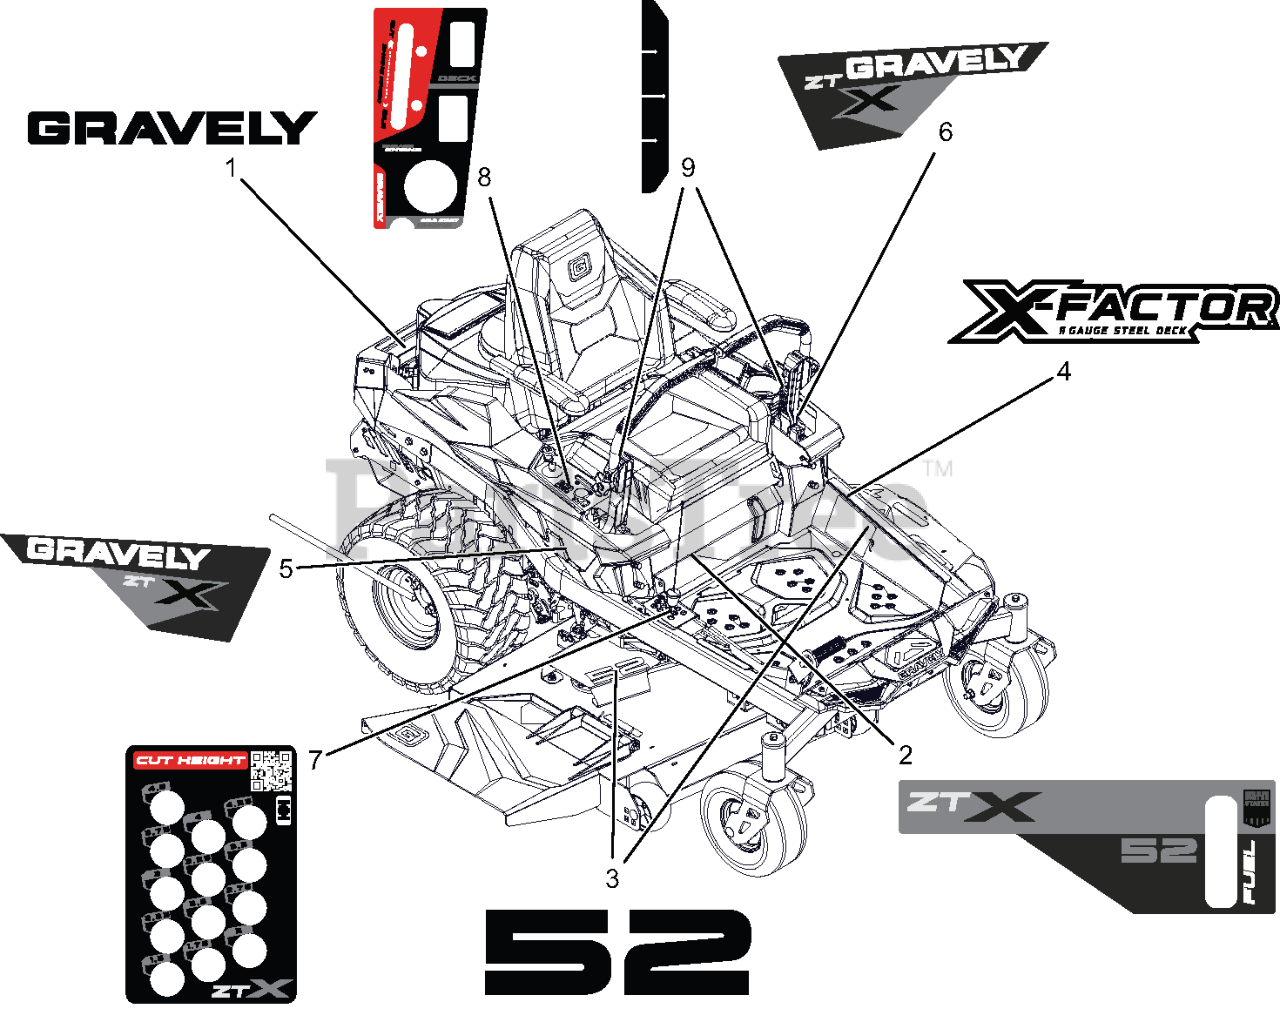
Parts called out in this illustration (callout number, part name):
1	DECAL- GRAVELY
2	DECAL- ZTX 52-KICK PLATE
3	DECAL- DECK 52"
4	DECAL- DECK X-FACTOR
5	DECAL- ZT X FENDER RH
6	DECAL- ZT X FENDER LH
7	DECAL- HEIGHT OF CUT-X
8	DECAL- CONTROL PANEL-GRAVELY
9	DECAL- HIRTH INDICATOR
